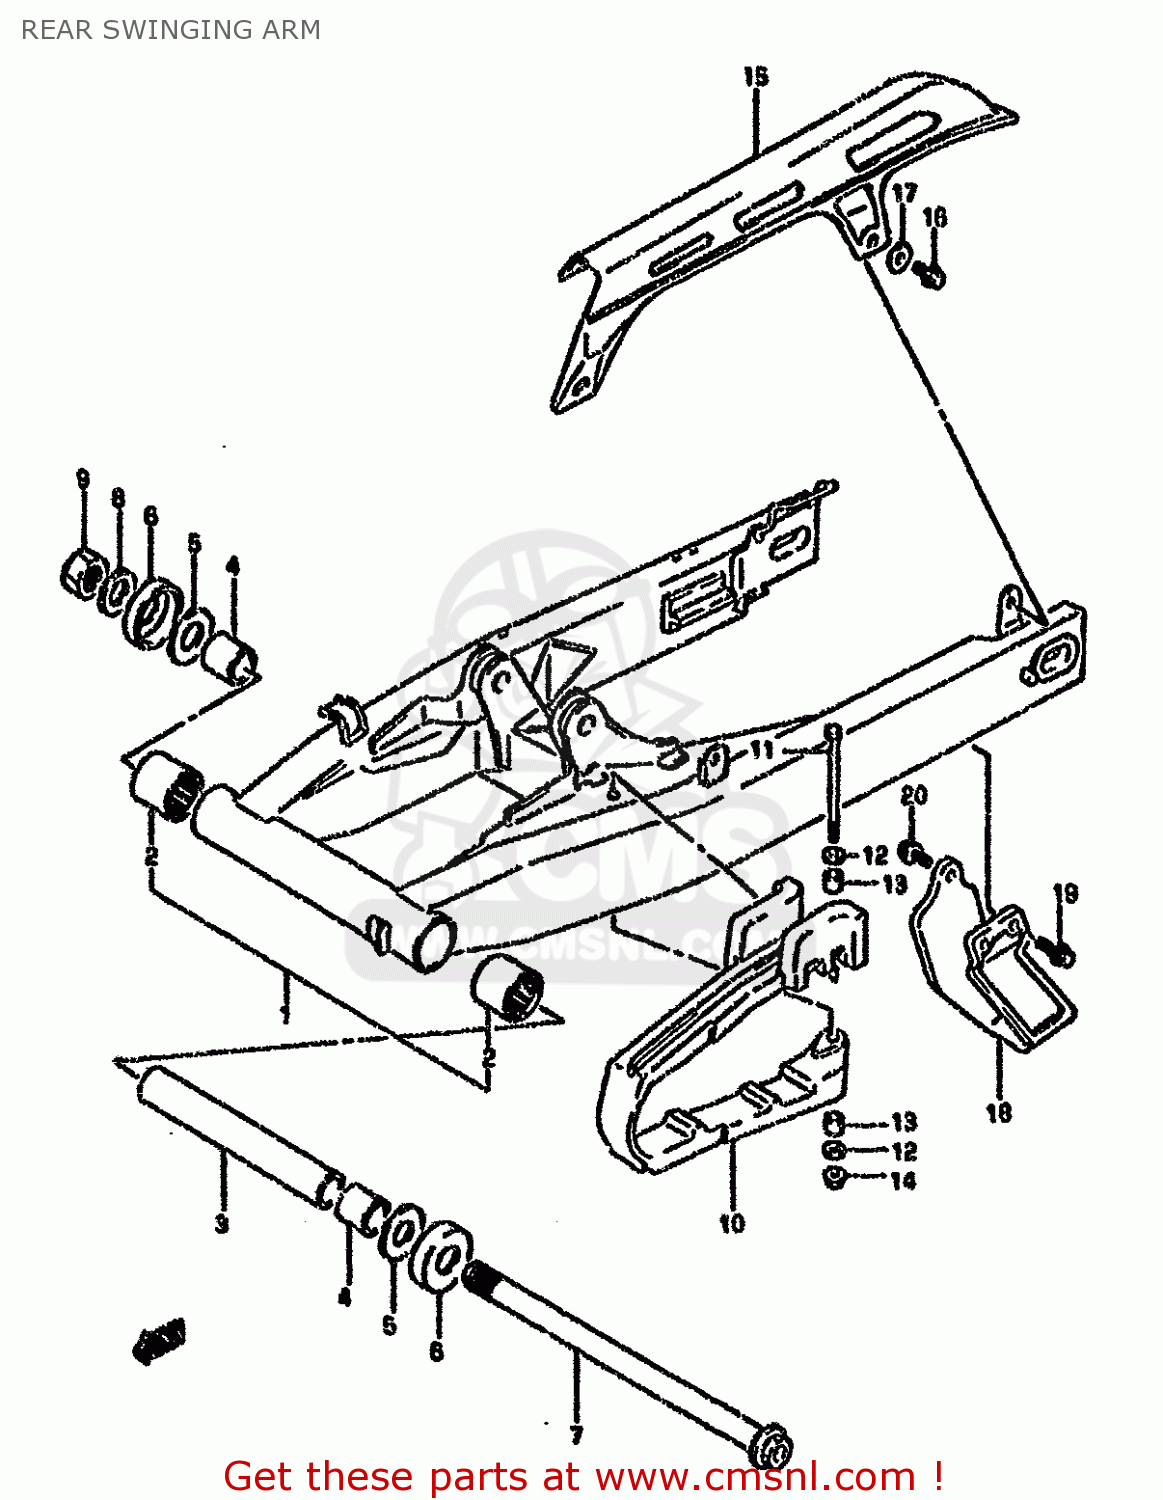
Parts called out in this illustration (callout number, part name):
1	SWING ARM ASSEMBLY,REAR
2	BEARING(22X29X20)
3	SPACER,RR SWGARM PIVOT CTR
4	SPACER,RR SWGARM PIVOT
5	WASHER
6	SEAL,RR SWGARM PIVOT DUST
7	SHAFT,REAR SWING ARM
8	WASHER
9	NUT 16MM
10	BUFFER,CHAIN TOUCH DEFENSE
11	BOLT,TOUCH DEFENSE FTG
12	WASHER (5.5X14X1.2)
13	SPACER (6.6X9X6.5)
14	NUT
15	CASE,CHAIN
16	BOLT
17	WASHER
18	GUIDE,CHAIN
19	BOLT
20	BOLT
